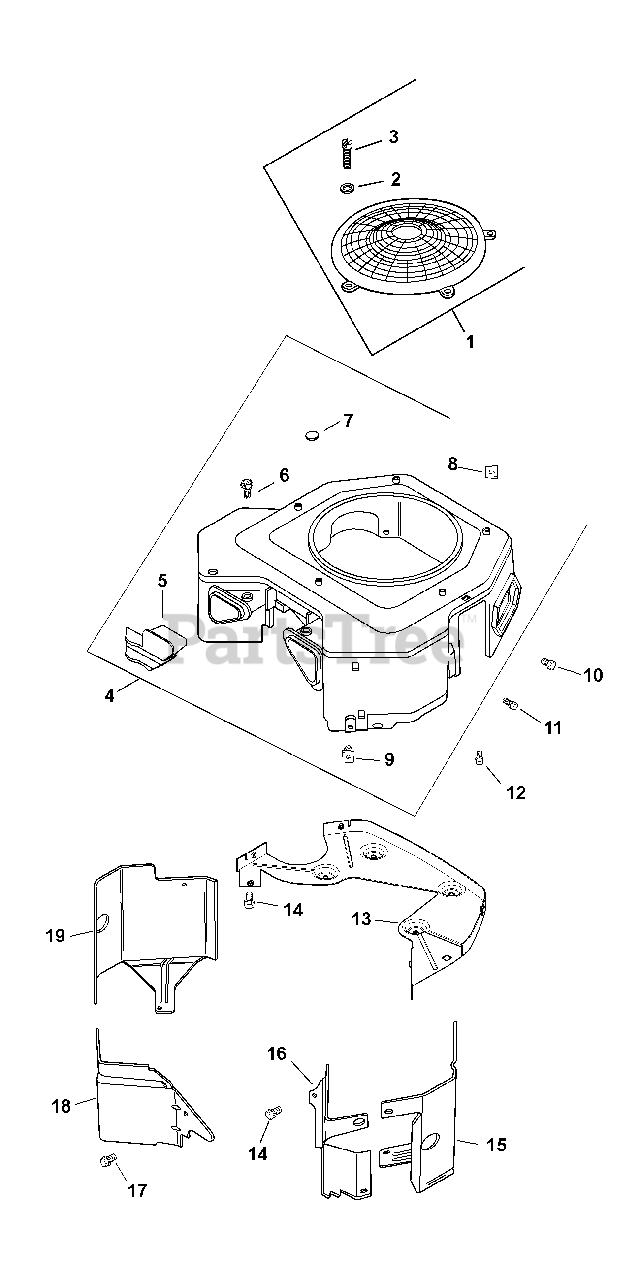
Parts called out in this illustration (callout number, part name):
1	Kit, Fixed Guard (Includes 2, 3,Decal & Insert)
2	Washer, Flat 7/32
3	Screw, Lbd Sckt Pan M5x0.8x10
4	Kit, Blower Housing Assembly
5	Cover, Blower Housing
6	Screw, Wsh Hd Tap #8-18 X 1/2"
7	Plug, Button 9/16
10	Screw, Flg Thd Frm M5 X .8 X 16
11	Screw, Flg Thd Frm M5 X .8 X 16
12	Screw, Flg Thd Frm M5 X .8 X 20
13	Kit, Backing Plate
14	Screw, Flg Thd Frm M6 X 1.0 X 16
15	Kit, Cyl Baffle-#2 Side
16	Baffle, Valley-#2 Side
17	Screw, Flg Thd Frm M5 X .8 X 10
18	Baffle, Valley #1 Side
19	Kit, Cyl Barrel - #1 Side
